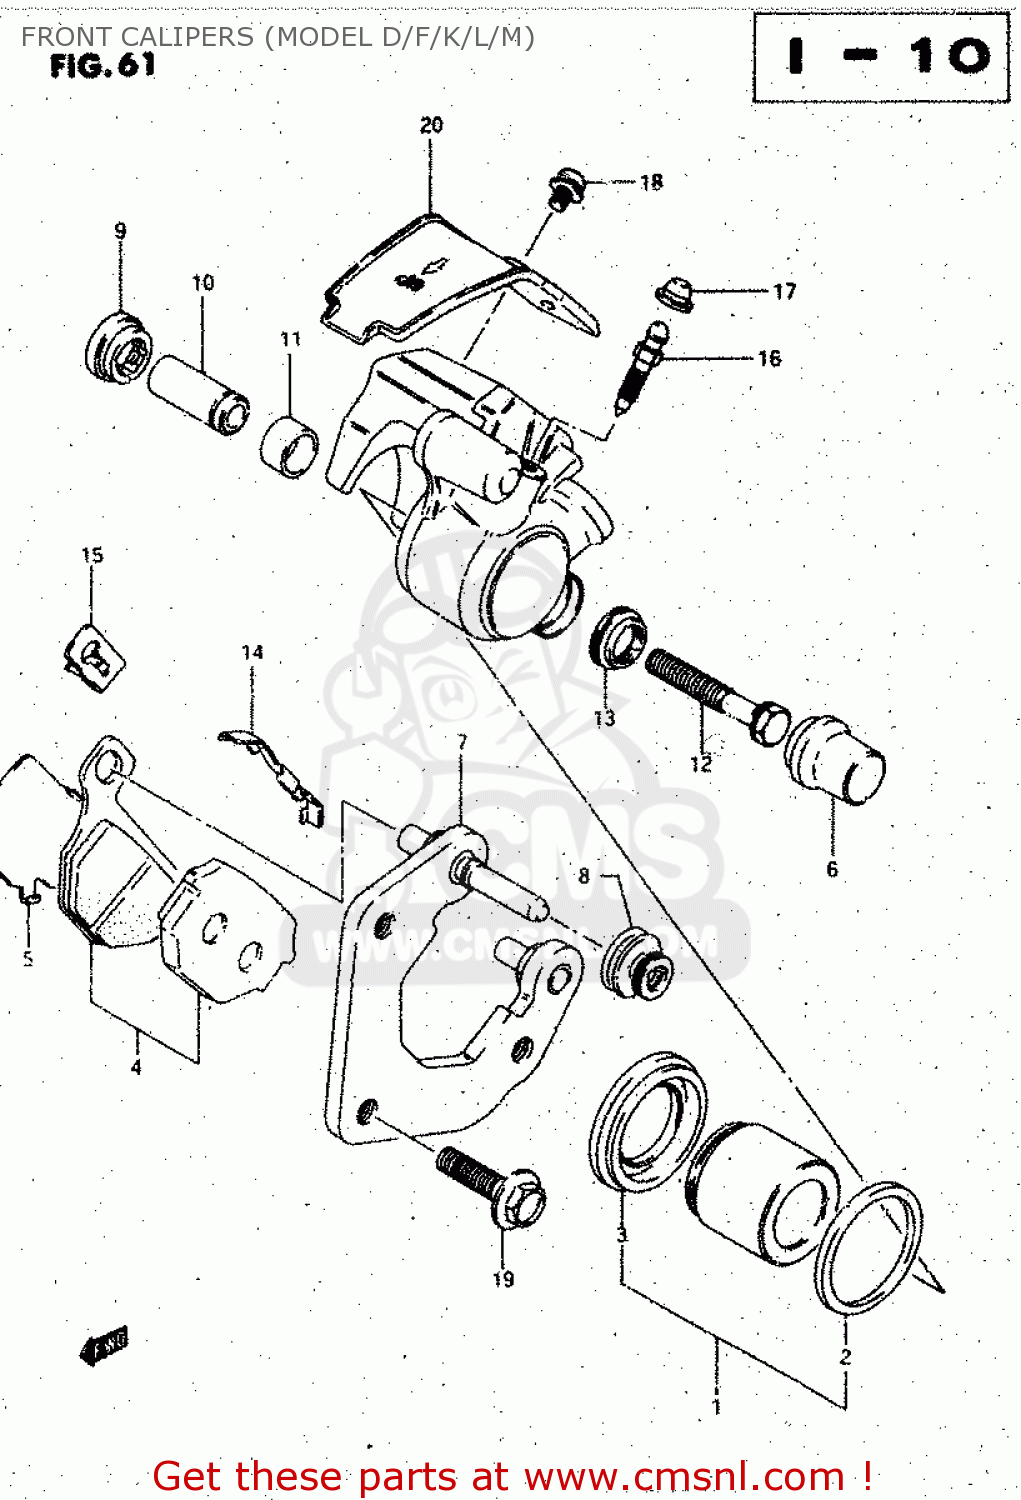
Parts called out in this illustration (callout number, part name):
1	PISTON SET
2	SEAL, PISTON
3	BOOT, PISTON
4	PAD SET
5	SHIM, PAD
6	CAP, BUSH
7	CARRIER SET,CALIPER
8	BOOT, GUIDE PIN
9	BOOT, BUSH DAST
10	BUSH, CYLINDER
11	COLLAR, BUSH
12	BOLT, BUSH
13	SEAL, CYLINDER
14	SPRING,PAD NO.1
15	SPRING,PAD
16	BREATHER
17	CAP,BREATHER
18	SCREW
19	BOLT 8X30
20	PROTECTOR,CALIPER
